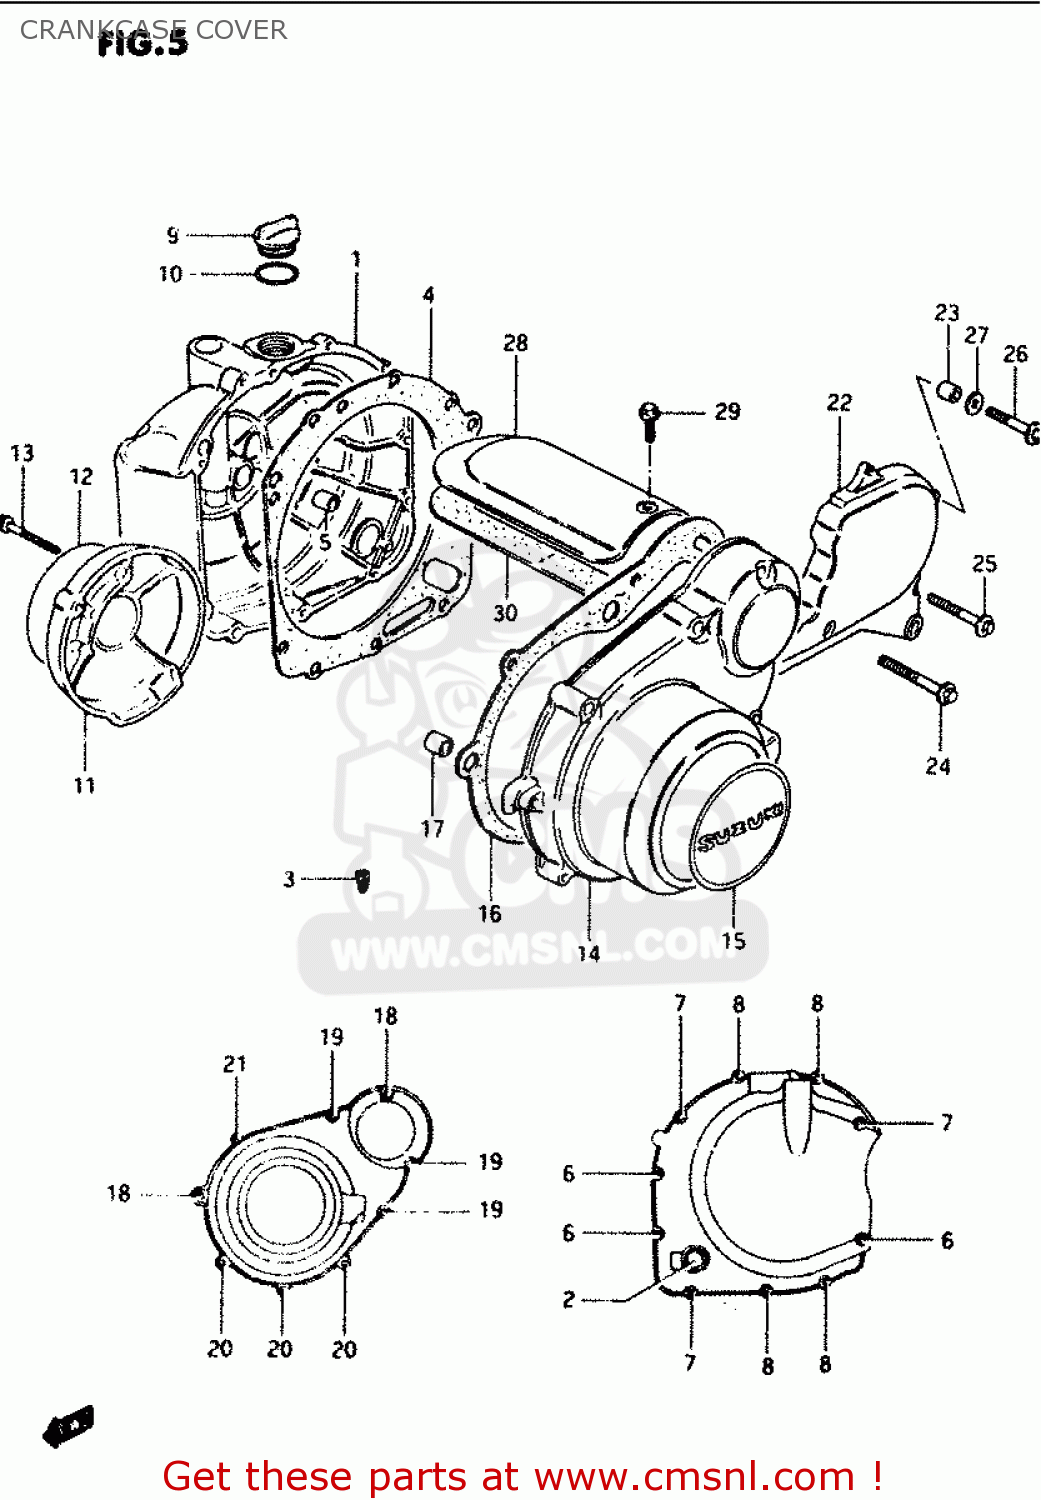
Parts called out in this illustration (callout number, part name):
1	COVER,CLUTCH
2	LENS,OIL LEVEL CHECK
3	JET
4	GASKET,MAGNETO COVER (N (MCA)
5	PIN
6	BOLT
7	BOLT
8	BOLT
9	PLUG SET
10	O RING(D:2.2,ID:32)
11	COVER,CONTACT BREAKER
12	EMBLEM,CONTACT BREAKER COVER
13	BOLT
14	COVER,MAGNETO
15	EMBLEM,MAGNETO COVER
16	GASKET,MAGNETO COVER (MCA)
17	PIN
18	BOLT
19	BOLT
20	BOLT
21	BOLT
22	COVER,SECONDARY DRIVE
23	PIN
24	BOLT
25	BOLT
26	BOLT (6X20)
27	WASHER
28	COVER,STARTER MOTOR
29	BOLT
30	GASKET,STARTING MOTOR COVER (NAS)
